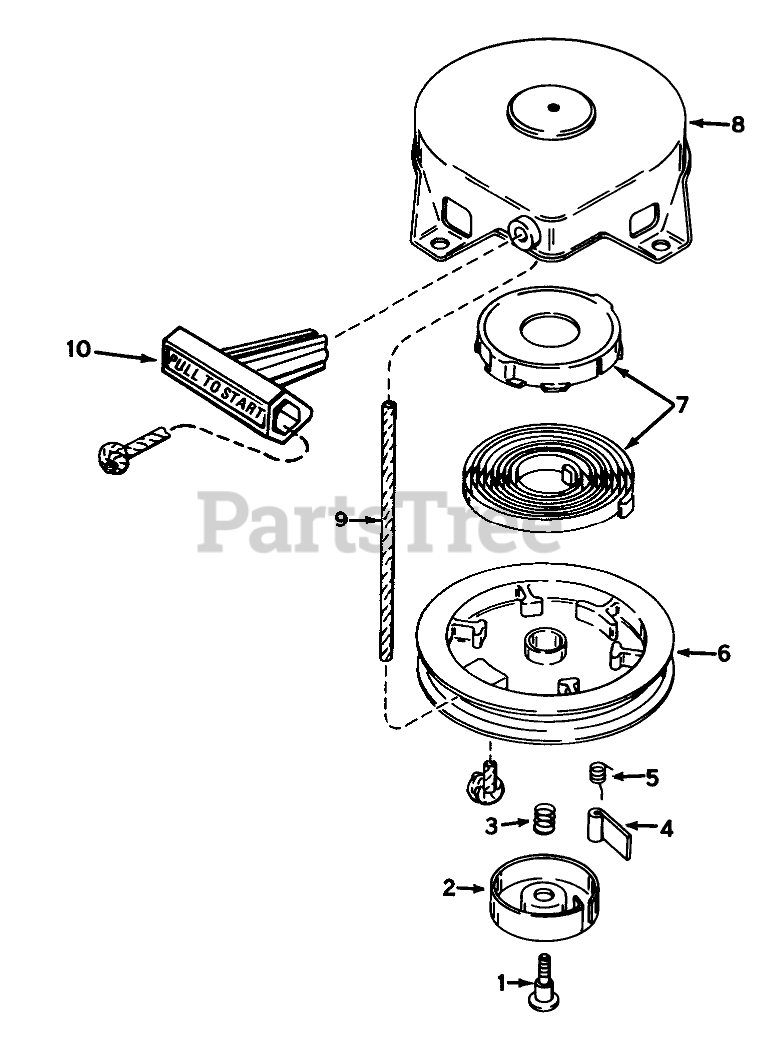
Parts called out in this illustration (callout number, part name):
2	Retainer
3	Spring-Brake
4	Dog-Starter
5	Spring-Dog
7	Spring & Keeper Assy
8	Housing-Starter
9	Rope-Starter (98 cut to length)
10	Handle-Starter
